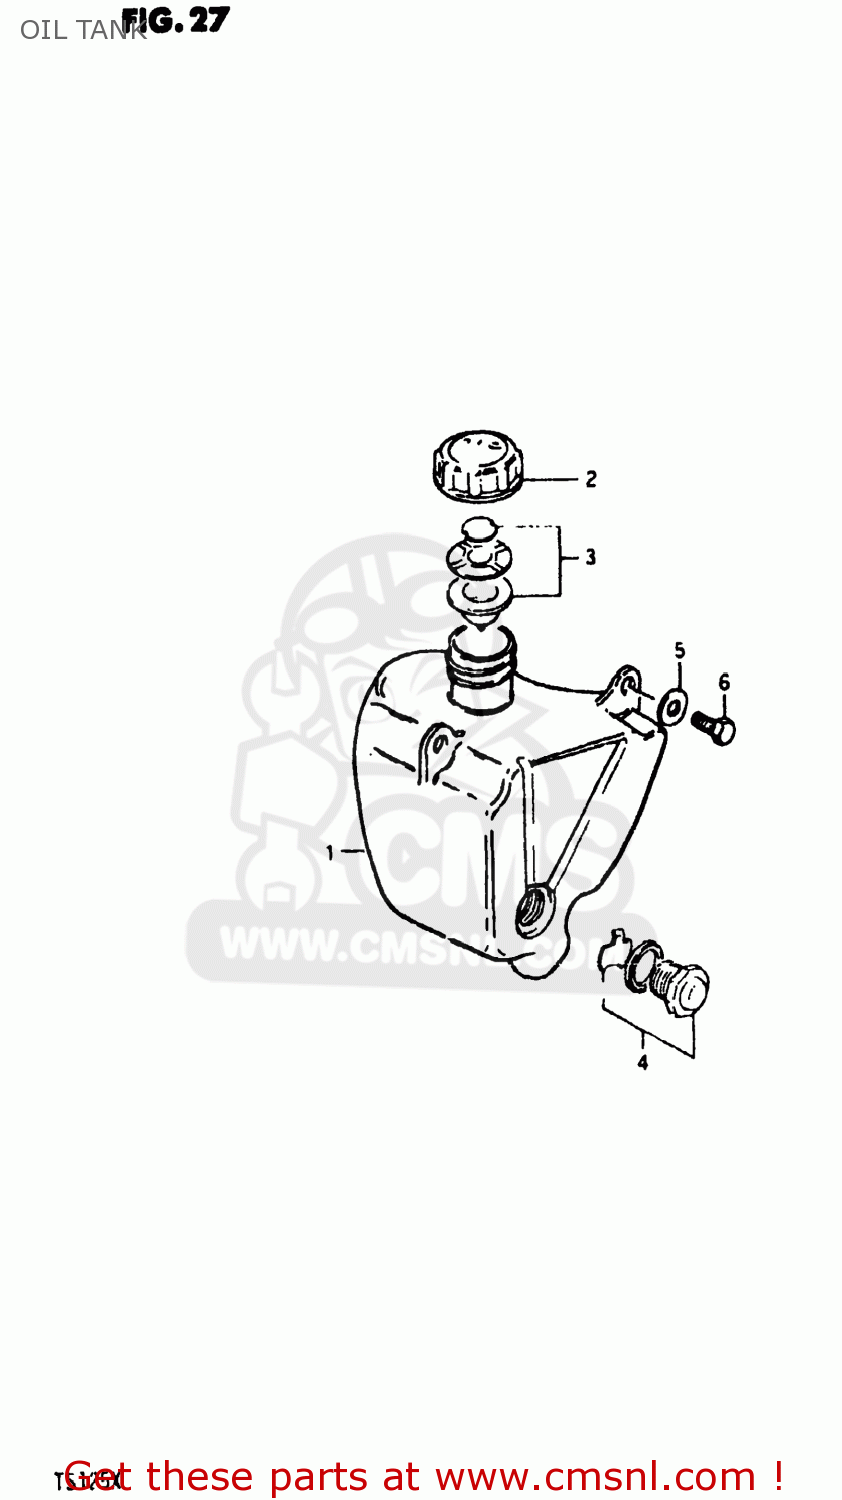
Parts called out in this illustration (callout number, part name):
1	TANK,OIL
2	CAP,OIL TANK
3	GASKET SET (NAS)
4	LENS SET,OIL LEVEL
5	WASHER
6	BOLT, UPPER
